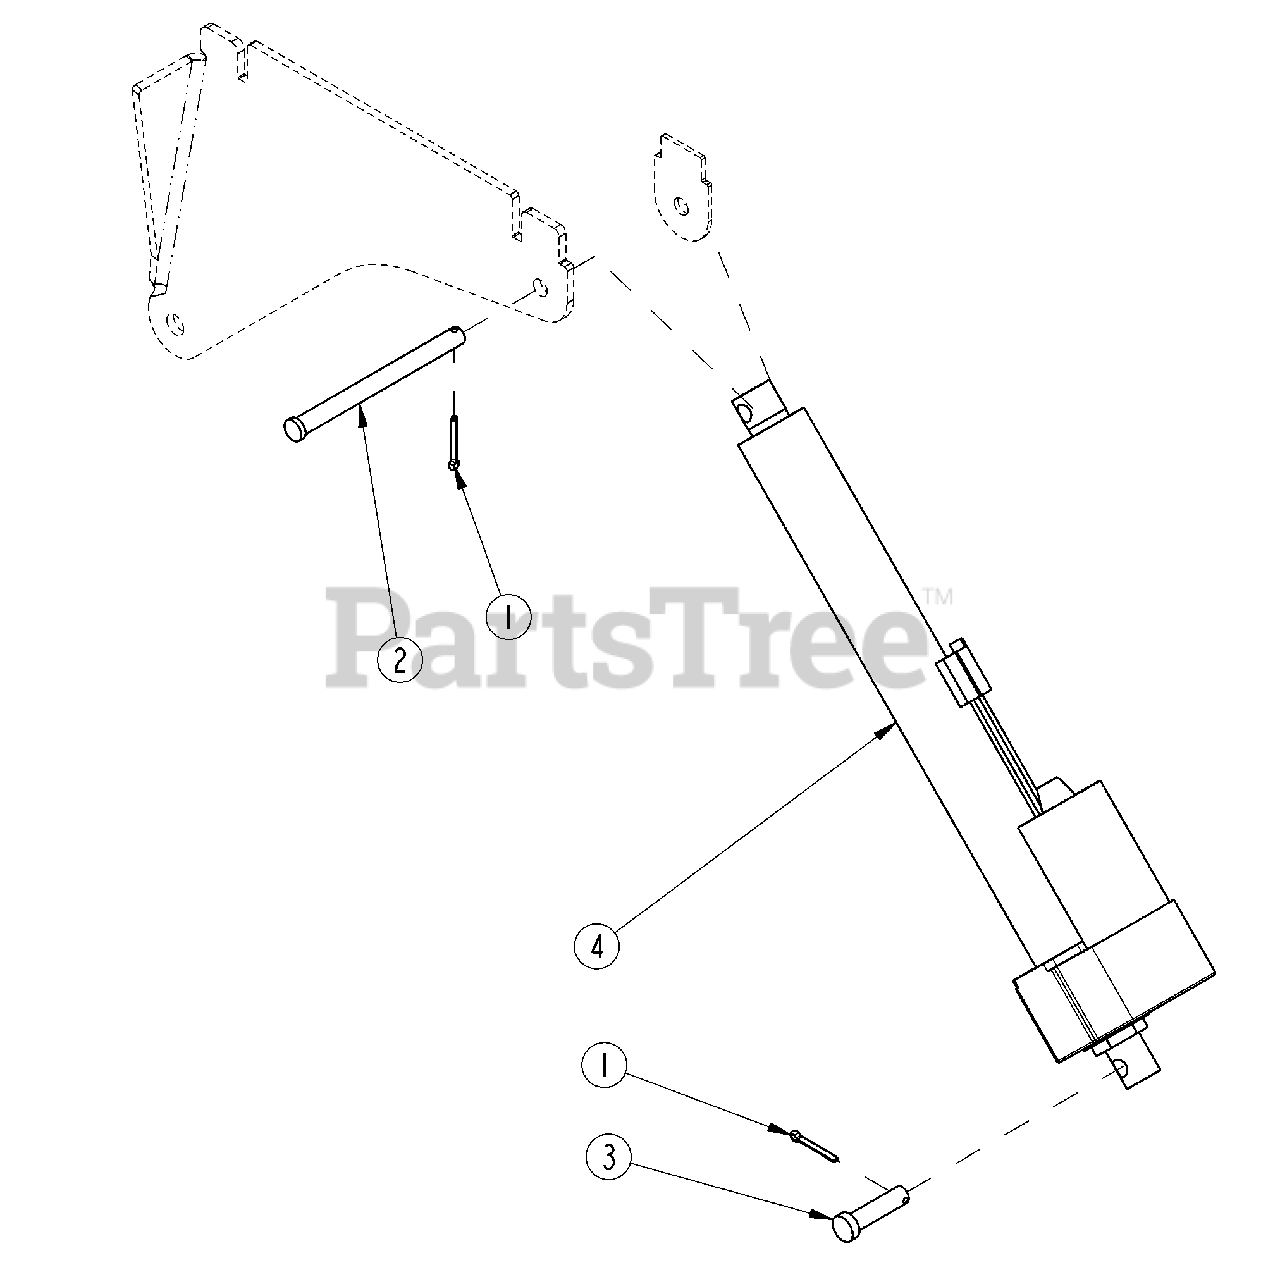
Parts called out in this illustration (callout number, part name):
1	RING, RUE .500 X .062 X 1.420
2	PIN-CLEV .50X6.00X5.76 YWZC
3	PIN-CLEV .50X2.00X1.77 YWZC
4	WARNER LINEAR ACTUATOR 12"STRK
